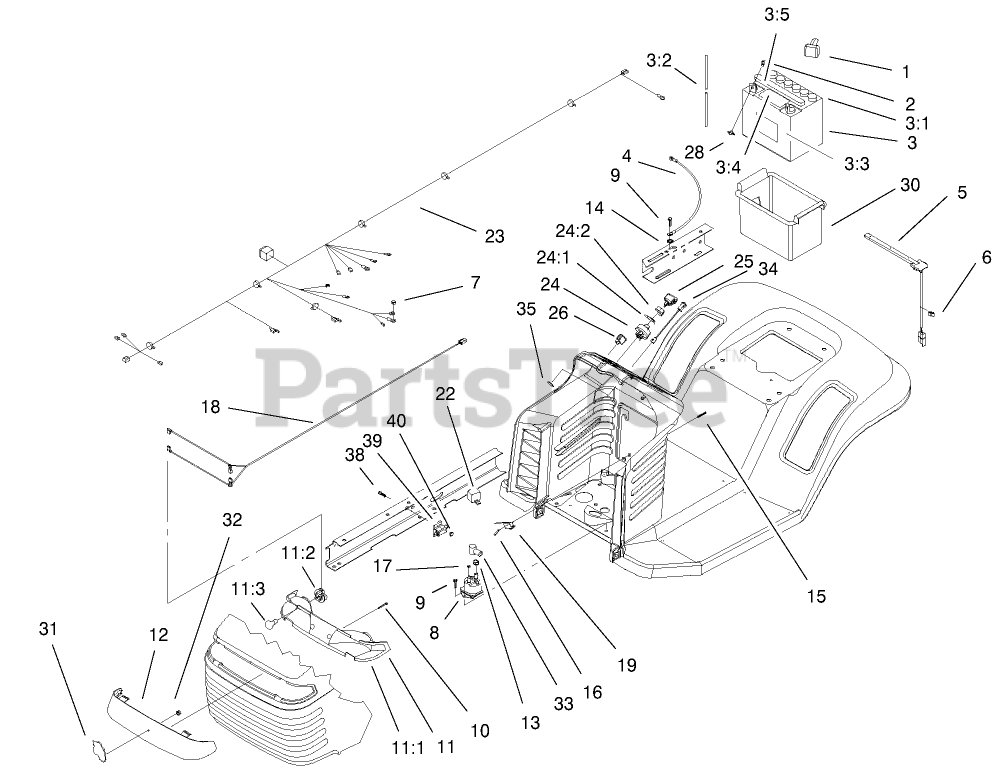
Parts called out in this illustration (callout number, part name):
1	BOOT-TERMINAL
2	SCREW-HH
3:1	CAP-BATTERY
3:2	TUBE-BATT DRAIN/80-2600
3:3	DECAL-BATTERY
3:4	DECAL-DANGER
3:5	DECAL - DANGER
4	WIRE ASM
5	SWITCH-SEAT
6	CLIP-RETAINER, WIRE
7	NUT-KEPS
8	SOLENOID
9	SCREW-HWH
11	HEADLIGHT REFLECTOR ASM
11:2	BULB
11:3	REFLECTOR-LIGHT
12	LENS-HEADLIGHT
13	NUT-KEPS
14	WASHER-LOCK/EXT
15	SCREW-HH
16	NUT-SPEED
17	NUT-KEPS
18	HARNESS-HEADLIGHT
19	SWITCH-MICRO
22	RELAY
24:1	WASHER-LOCK
24:2	NUT-HH
25	KEY-IGNITION
26	SWITCH-ROCKER
28	NUT-WING
30	BOX-BATTERY
33	BOOT-TERMINAL INSULATOR
34	LIGHT-INDICATOR
38	SCREW-HSH
40	NUT-LOCK, NI
